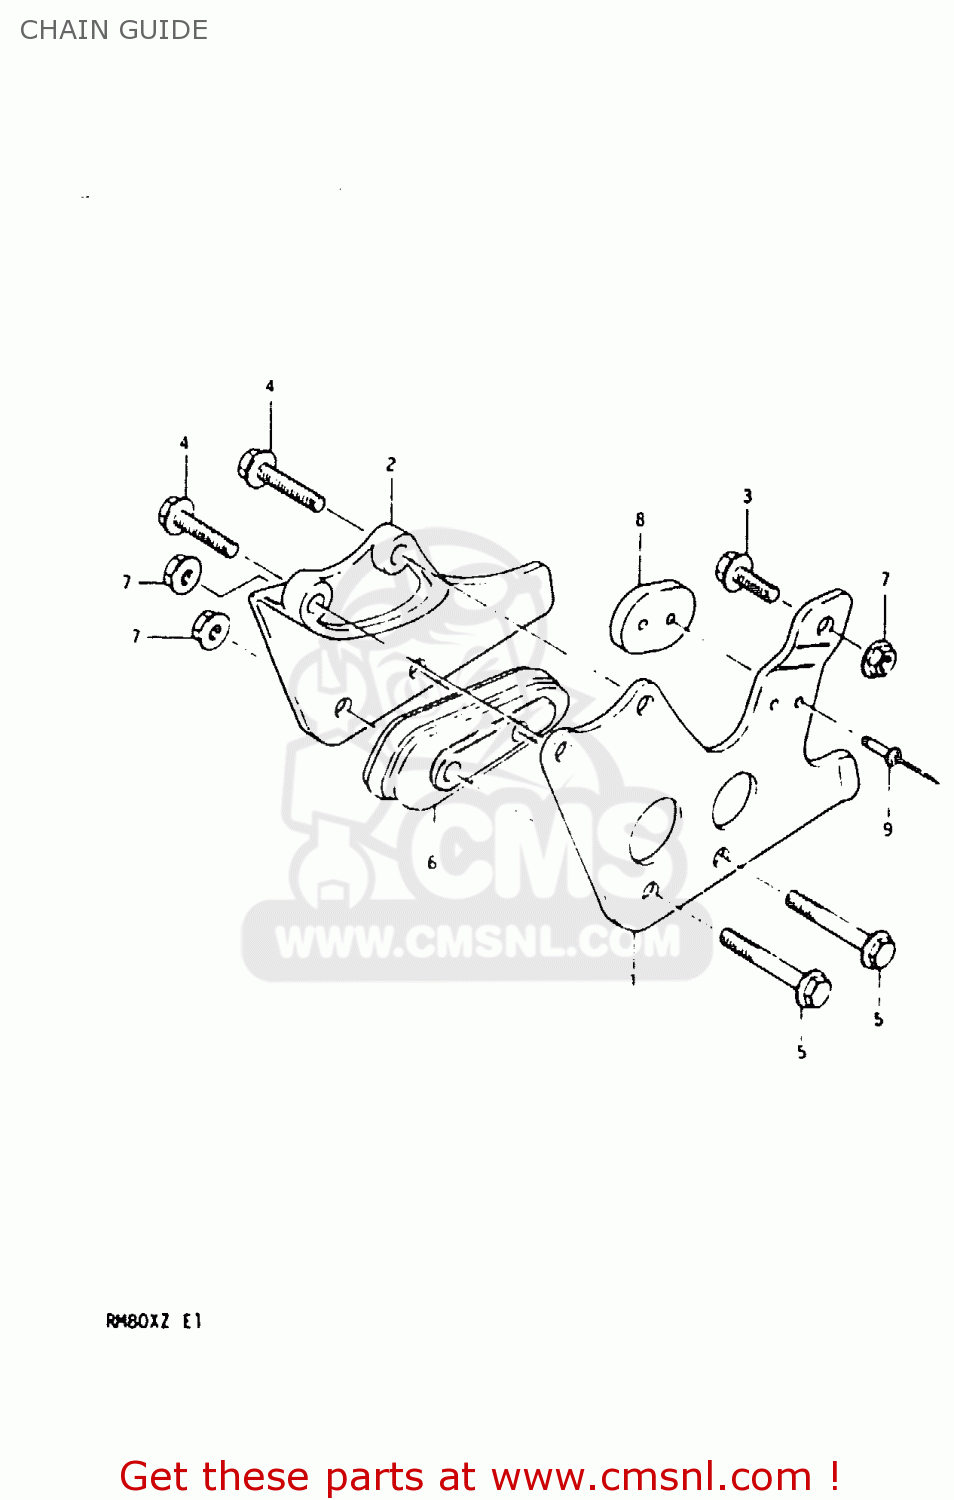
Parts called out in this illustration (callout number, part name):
1	GUIDE,CHAIN
2	PLATE,CHAIN GUIDE INNER
3	BOLT
4	BOLT
5	BOLT
6	DEFENSE,CHAIN GUIDE
7	NUT
8	PAD,DRIVE CHAIN GUIDE
9	RIVET
